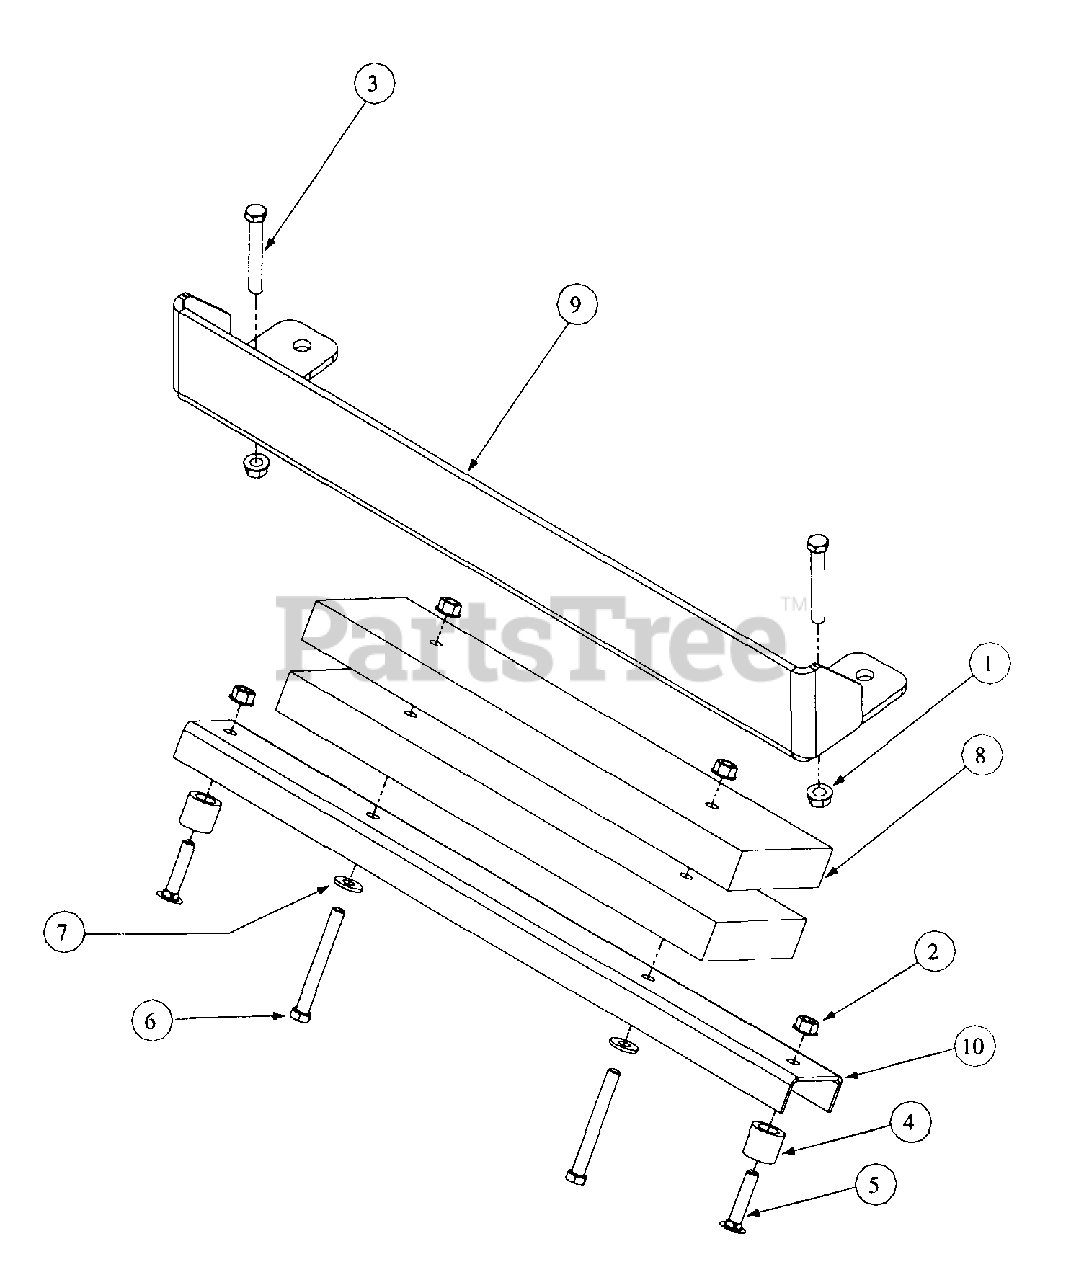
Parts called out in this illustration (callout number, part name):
1	Hex Nut, 1/2-13, Insert Lock
2	Nut, Hex 3/8-16 Flange Lock
3	HHCS, 1/2-13, 3.00
4	Spacer Crossbar
5	Carriage Bolt, 3/8-16, 1.75
6	HHCS, 3/8-16, 3.25
7	Flat Washer, .406 ID x 1.0 OD x .105
8	Bar, Weight
9	Rear Bumper Plate
10	Bumper Cross Bar-Rear
